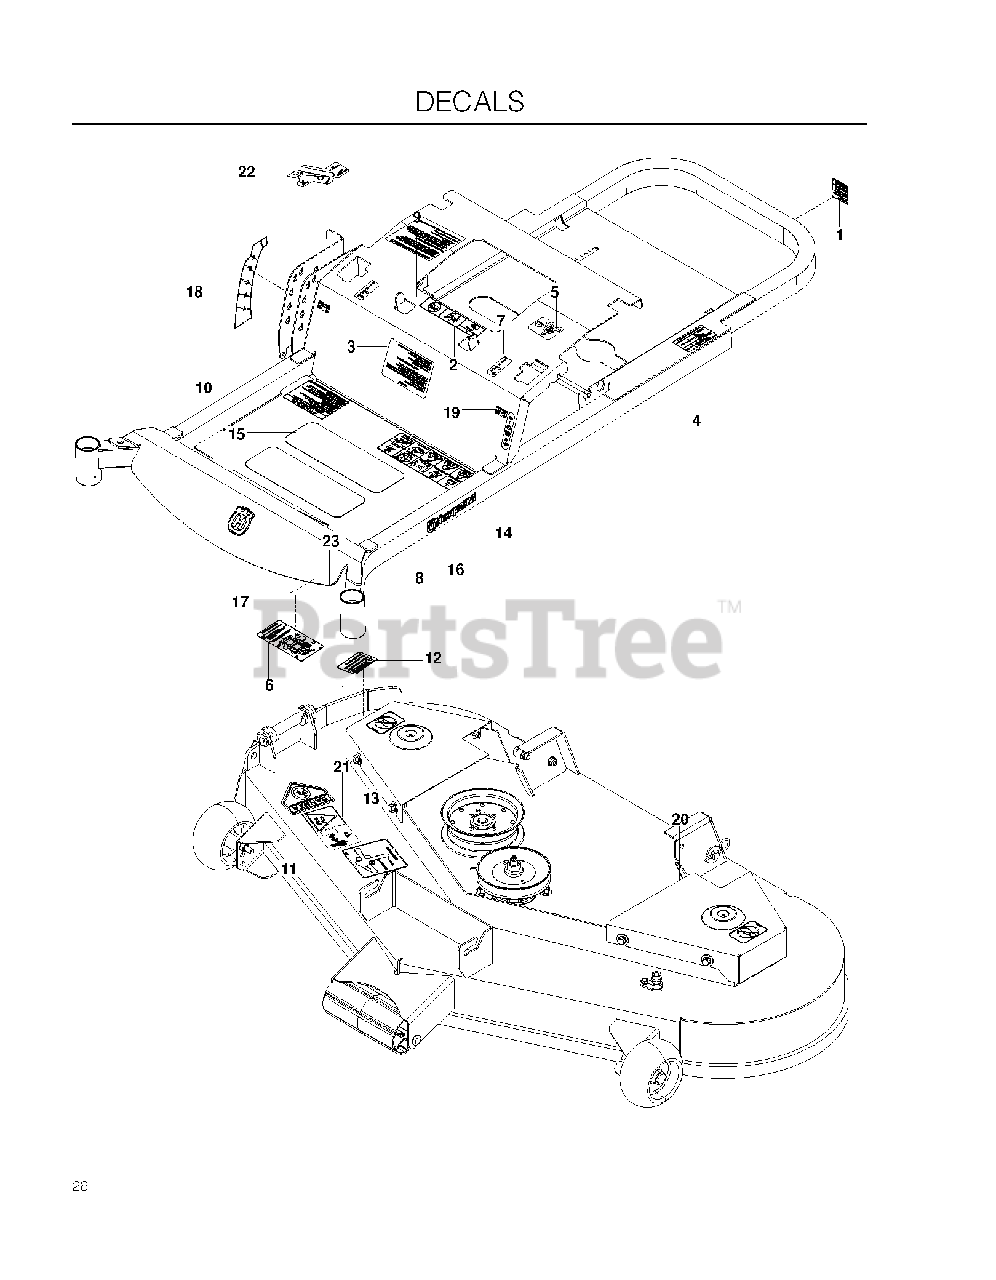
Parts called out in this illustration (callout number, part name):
1	DECAL, PROP. 65
2	EURO DECAL-BATTERY WARNIN6
3	DECAL, START
4	DECAL, DO NOT TOW
5	DECAL, EXITING MOWER
6	DECAL, SERVICE
7	DECAL, MOTION CONTROL
8	DECAL, SAFETY WARNING
9	DECAL, CUSTOMER RESPNSIBILITY
10	DECAL, WARNING
11	DECAL, CPSC
12	DECAL, CAUTION
13	DECAL, BELT ROUTING
14	DECAL, PARK BRAKE
15	ANTI-SKID PAD
16	RP.DECAL.BADGE.170MM.TEXTLOGO
17	DECAL.AUGER.HUSQ.CROWN.SNOW
18	DECAL, DECK HEIGHT, HUSQ
19	DECAL, F.S.T.
20	DECAL, NO STEP
21	DECAL, EURO SEVERING
22	DECAL, CTRL PANEL, HUSQ
23	DECAL RZ4824F
